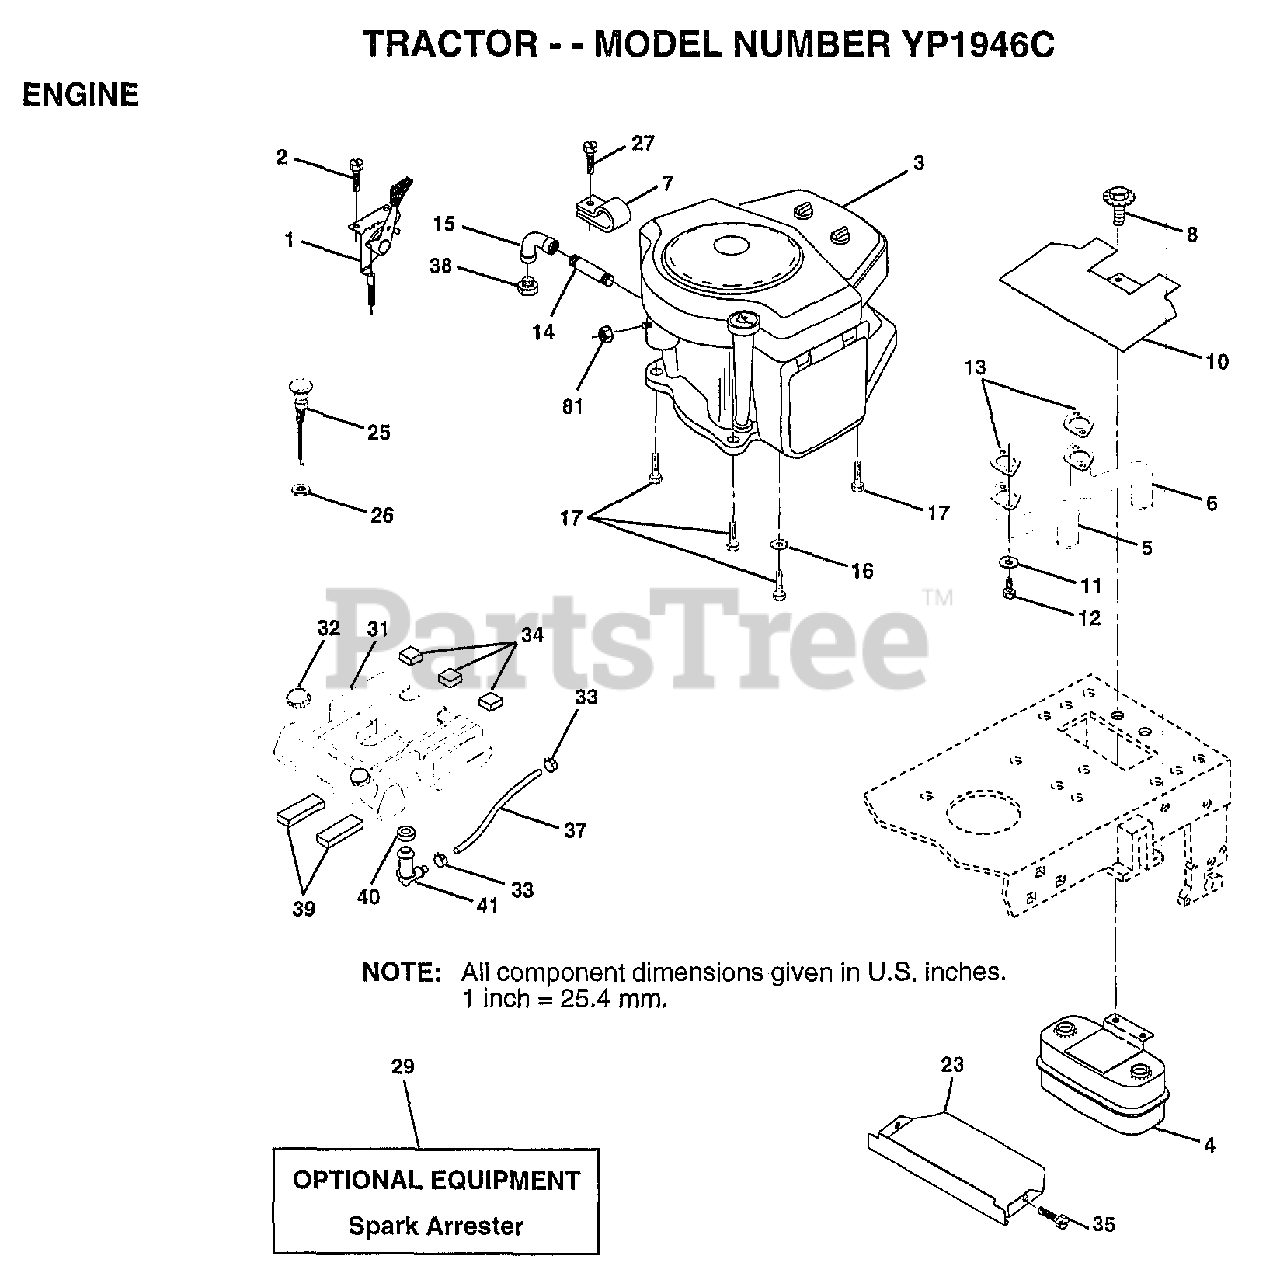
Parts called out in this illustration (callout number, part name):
1	CONTROL THRT 35.5
2	SCREW LT
4	MUFFLER.TW.LOTONE
5	EXHAUST.B&S.18.LH
6	EXHAUST.B&S.18.RH
7	CLAMP.TUBE.DBL.EN
8	BOLT.5/16-18.UNC
10	SHIELD.HEAT.
11	LOCKWASHER
13	GASKET MUFFLER
14	PIPE NIPPLE LT
15	ELBOW
16	LOCKWASHER
17	SCREW LT
23	SHIELD.BRN/DBR.GD
25	CONTROL.CHOKE.37
26	"NUT,KEPS 3/8-24IM"
27	"SCREW-TT,10-32 FL"
31	TANK FUEL REAR
32	CAP ASM FUEL
33	HOSE CLAMP
34	PAD-SPACER LT
35	SCREW
37	FUEL LINE T
39	PAD IDLER TI
40	BUSHING OUTLET T
41	STEM.TANK.FUEL
81	NUT
